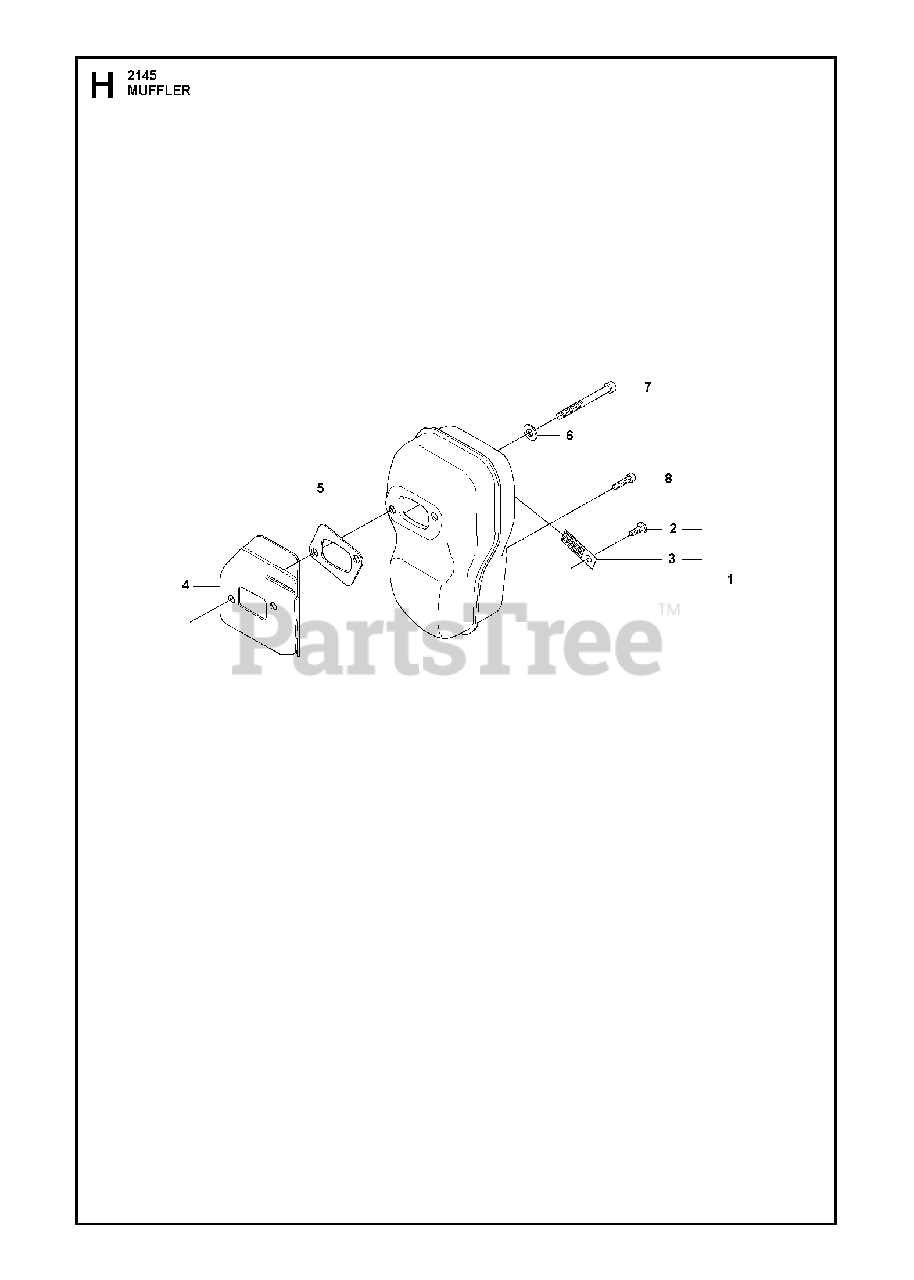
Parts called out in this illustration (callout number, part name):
1	MUFFLER
2	SCREW
3	SCREEN
4	DEFLECTOR
6	DOUBLE WASHER
8	SCREW IHSCFM
